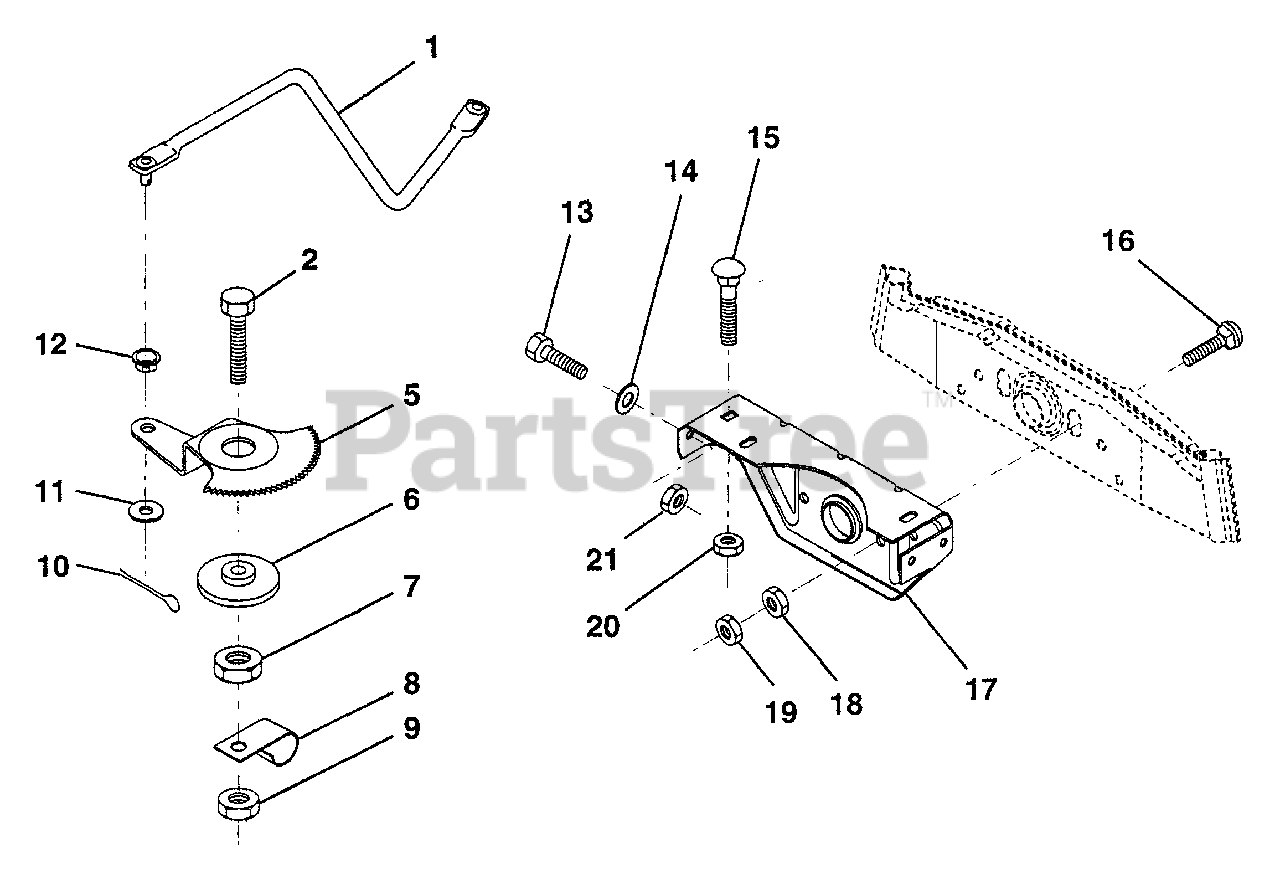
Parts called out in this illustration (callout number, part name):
1	Link, Drag
2	Bolt, Hex, Fin. 1/2-13 x 1-3/4
5	Gear, Sector
7	Nut, Heavy Hex, Top Lock 1/2-13 UNC
8	Clip, Insulated
9	Nut, Crownlock 3/8-16
10	Pin, Cotter 1/8 x 3/4
11	Washer 13/32 x 13/16 x 16 Ga.
13	Bolt, Hex Head 5/16-18 UNC x 3/4
14	Washer 11/32 x 7/8 x 16 Gauge
15	Bolt, Carriage 3/8-16 UNC x 3/4
16	Bolt, Carriage
17	Support, Front Axle
18	Nut, Hex, Fin. 3/8-16 UNC
19	Nut, Centerlock 3/8-16 UNC
20	Nut, Crownlock 3/8-16 UNC
21	Nut, Crownlock 5/16-18
